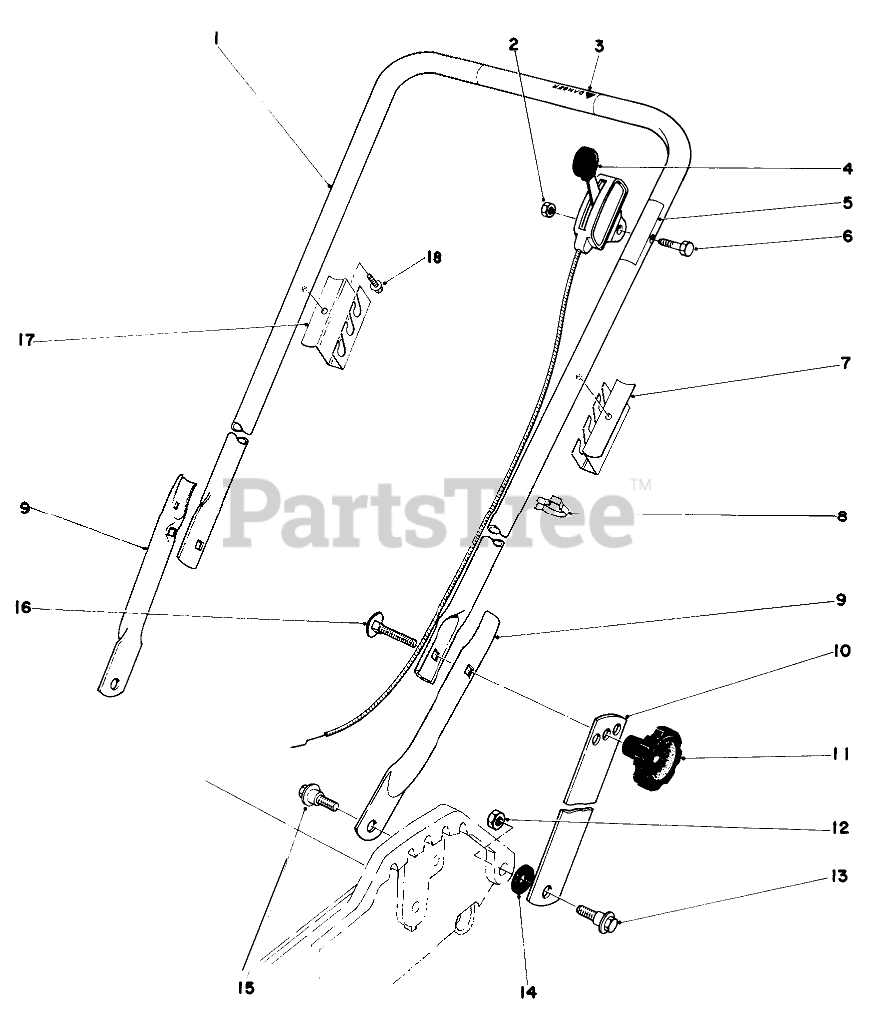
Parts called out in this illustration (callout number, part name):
1	Handle-Upper
2	NUT-LOCK
3	Decal
4	Throttle Control
5	Decal-Throttle
6	SCREW-HH
7	SUPPORT BAG LH
8	BOWDEN CLIP
9	Hand-Lower
10	18" HANDLE LATCH
12	Nut
13	SCREW-SHOULDER
14	SPACER
15	SCREW-SHOULDER
16	SCREW-HANDLE
17	SUPPORT BAG RH
18	SCREW-HWHTF
